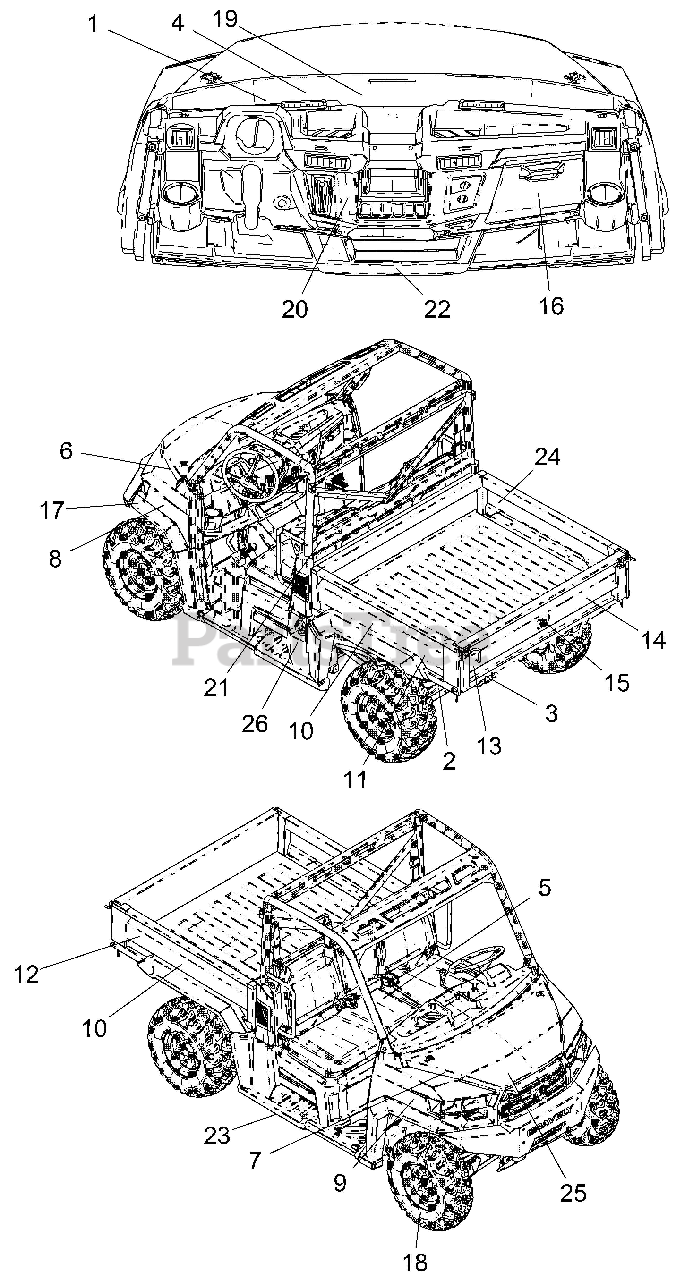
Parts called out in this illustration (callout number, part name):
1	DECAL, AGE WARNING 16
2	DECAL, REFLECTOR RED
3	DECAL-WARNING,TRAILER LOAD
4	LABEL, OPEI COMPLIANCE
5	DECAL, WARNING, PULLEY
6	DECAL, HOOD TOP DIESEL LH
7	DECAL, HOOD TOP DIESEL RH
8	DECAL, HOOD SIDE ATLSJSV, LH
9	DECAL, HOOD SIDE ATLSJSV, RH
10	DECAL, BOX SIDE GRAVELY
11	DECAL, BOX SIDE 3000 LH
12	DECAL, BOX SIDE 3000 RH
13	DECAL, TAILGATE ATLSJSV, LH
14	DECAL, TAILGATE AWD RH
15	DECAL, TAILGATE GRAVELY CENTER
16	DECAL, GLOVEBOX COVER
17	DECAL, REFLECTOR AMBER LH
18	DECAL, REFLECTOR AMBER RH
19	DECAL, WARNING DISC GRAVELY
20	DECAL, CAUTION SHIFT/BRAKE
21	DECAL, ROPS GRAVELY 3000
22	DECAL,WARNING PASS/TIRE PRESS
23	DECAL NOT A STEP
24	DECAL-WARN,NEVER CARRY FUEL
25	DECAL-COOLANT
26	DECAL, WARN FUEL TRANSPORT
